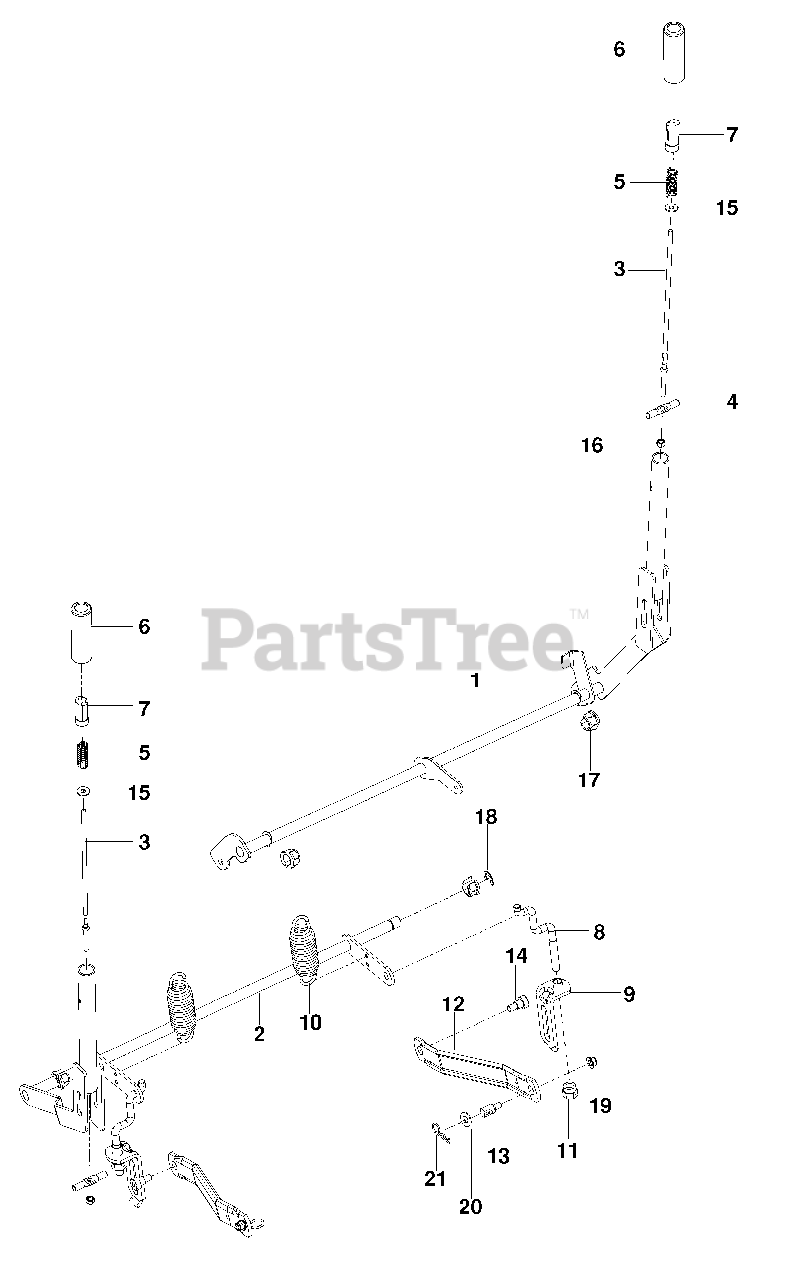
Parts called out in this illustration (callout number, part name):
1	SHAFT, BRAKE
2	SHAFT, LIFT
3	ROD, HANDLE RELEASE
4	ROD, LATCH RELEASE
5	SPRING, COMPRESSION
6	GRIP, HANDLE
7	BUTTON, PUSH
8	LINK, REAR SUSPENSION
9	BRACKET, CENTERING LNK
11	NUT, LIFT LINK
12	ARM, SUSPENSION RR
13	STUD w/ANTI- ROTATE
14	BOLT 3/8-16 x 3/8 SKT HD
15	WASHER 1/4 FLAT
16	NUT 1/4-20 HEX NYLOC
17	PLASTIC NUT
19	NUT 5/16-18 FLANGE NYLOC
20	WASHER 5/8 FLAT SAE
21	HAIRPIN #4
